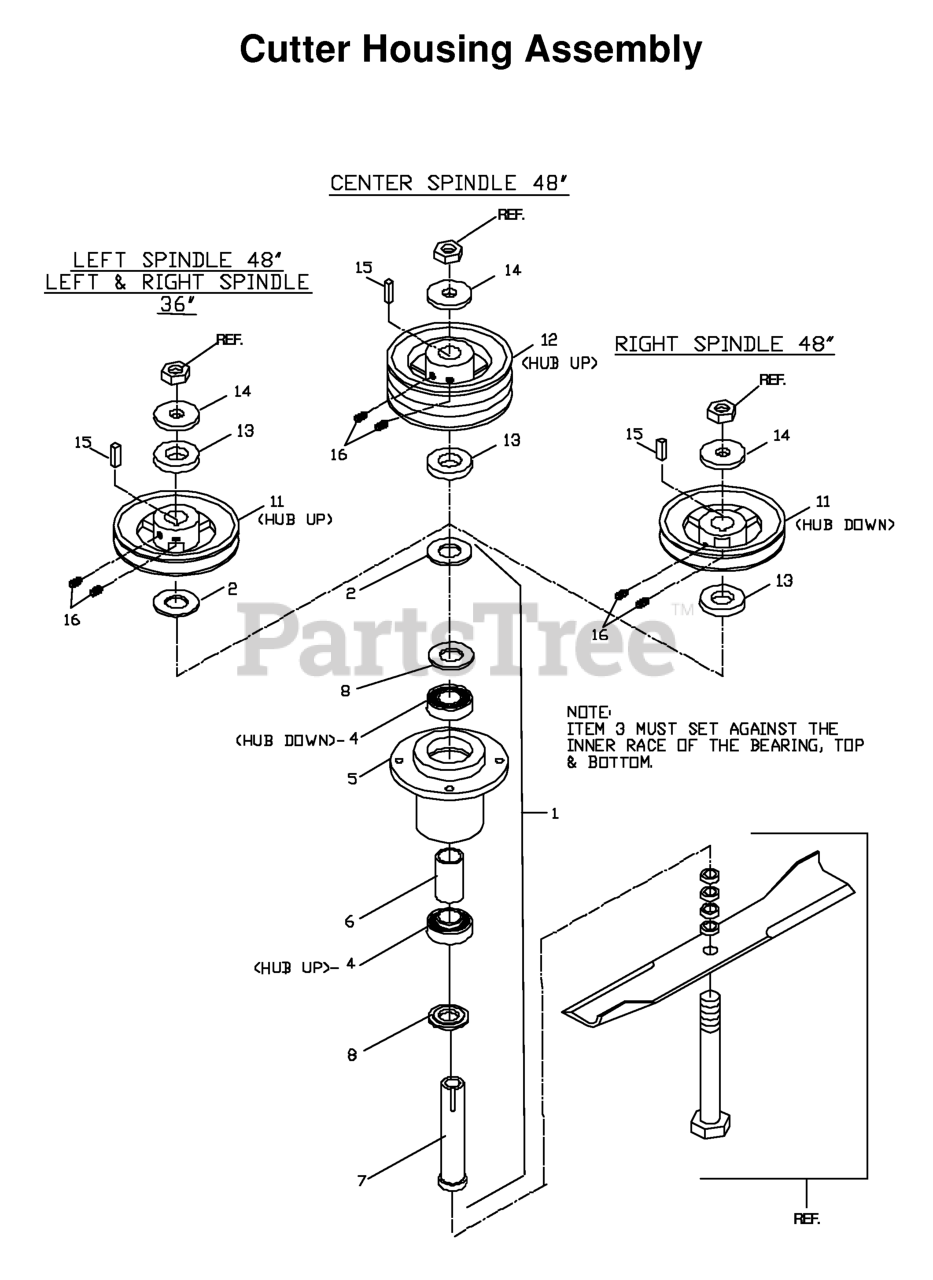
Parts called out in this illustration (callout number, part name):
1	HOUSING ASSEMBLY
2	MACHINERY BUSHING 10 GA.
4	BEARING
7	SPINDLE SHAFT
8	COMBO SPACER
11	PULLEY W/SETSCREWS
12	PULLEY, DOUBLE W/SETS
14	WASHER, SUPPORT
15	KEY 1/4 SQ X 1 1/8
16	SET SCREW 5/16 NYLOC
